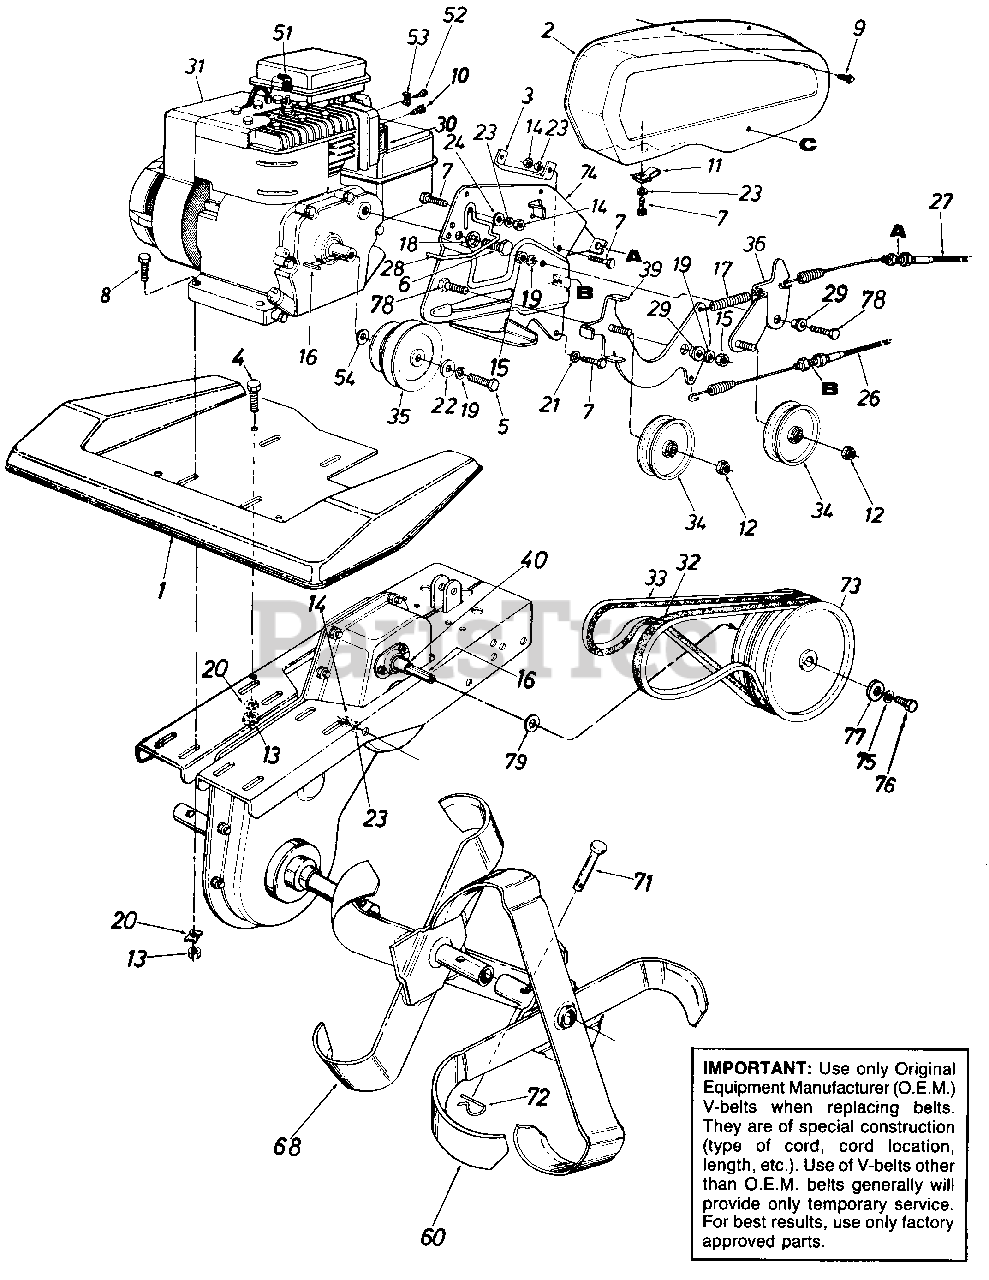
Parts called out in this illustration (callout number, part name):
4	Hex Bolt 5/16-18 x .75" Lg.
5	Hex Bolt 3/8-24 x 1.25" Lg.
6	Hex Bolt 5/16-24 x .62" Lg.
7	Hex Bolt 1/4-20 x .85" Lg.
8	Hex Bolt 5/16-18 x 1.5" Lg.
9	Hex Wash. Hd. Tap Scr. 1/4-20 x .5" Lg.
10	Hex Wash. Hd. Slotted Scr. #8-32 x .38"
11	Speed Nut 1/4-20 Thd.
12	Hex L-Nut 3/8-24 Thd.
13	Hex Nut 5/16-18 Thd.
14	Hex Nut 1/4-20 Thd.
15	Hex L-Nut 3/8-16 Thd.
16	Sq. Key 3/16 x 1.5" Lg.
17	Extension Spring 2.03 Lg.
18	L-Wash. 5/16" I.D.
19	L-Wash. 3/8" I.D.
20	Spec. L-Wash. 5/16" I.D.
21	Spr. Wash. .265" I.D. x .562" O.D.
22	Fl-Wash. 3/8" I.D. x 1" O.D. x 1.27"
23	L-Wash. 1/4" I.D.
24	Fl-Wash. .25 I.D. x .62 O.D.
26	Clutch Control Cable
27	Clutch Control Cable
28	Belt Guard Rod
29	Shld. Spacer .380 I.D.
30	Muffler Deflector
31	Engine
32	V-Belt
33	V-Belt
34	Fl-Idler w/Flanges 3.12 O.D. x .75
35	Engine Pulley
40	Spacer .635 I.D.
51	Spark Plug Boot
52	Hex Sems Scr. #10-32 x .62" Lg.
53	Casing Clamp
54	Fl-Wash. .75" I.D. x 1.5" O.D. x .12"
72	Intern. Cotter Pin
73	Transmission Pulley 6" Dia.
74	Clutch Mtg. Plate
75	L-Wash. 5/16" I.D.
76	Patch Bolt 5/16-18 x 1 " Lg.
77	Fl-Wash. 5/16" I.D.
78	Hex Bolt 3/8-24 x 1.0" Lg. (Grade 5)
79	Fl-Wash. .635" I.D. x 1.25" O.D.
